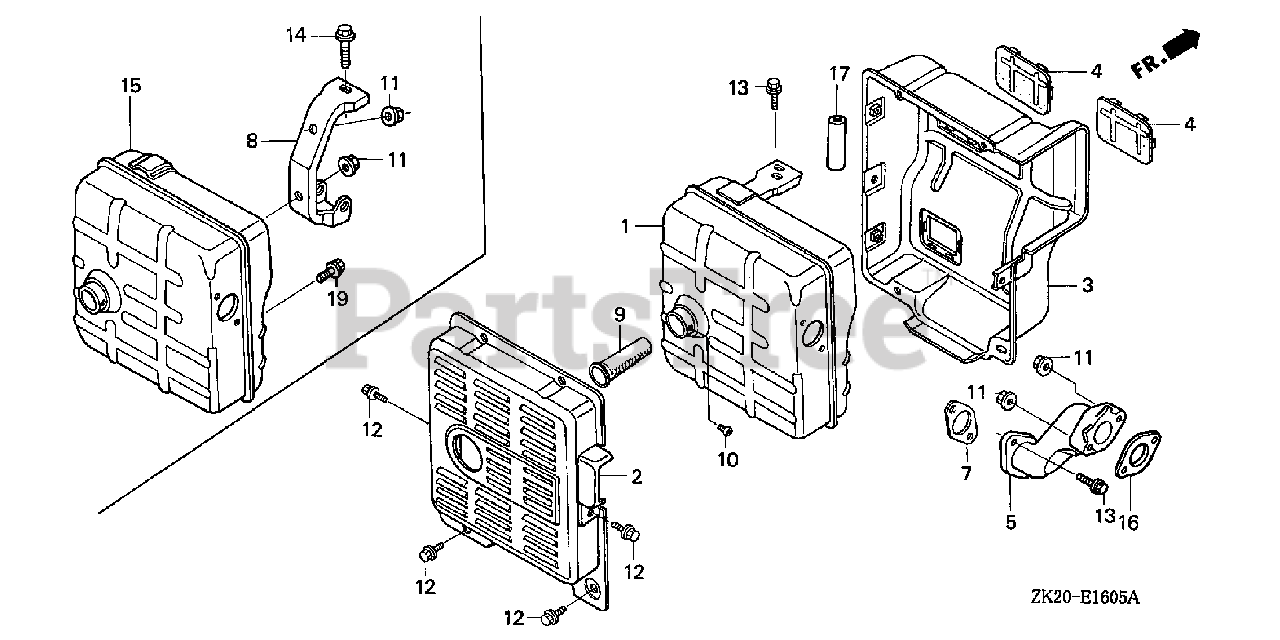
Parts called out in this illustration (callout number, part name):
1	MUFFLER
2	PROTECTOR, MUFFLER (OUTER)
3	PROTECTOR, MUFFLER (INNER)
4	SEAL, MUFFLER PROTECTOR
5	PIPE, EX.
7	GASKET, EX. PIPE
9	ARRESTER, SPARK
10	SCREW, TAPPING (4X8)
11	NUT, FLANGE (8MM)
12	BOLT, FLANGE (6X12)
13	BOLT, FLANGE (8X20)
